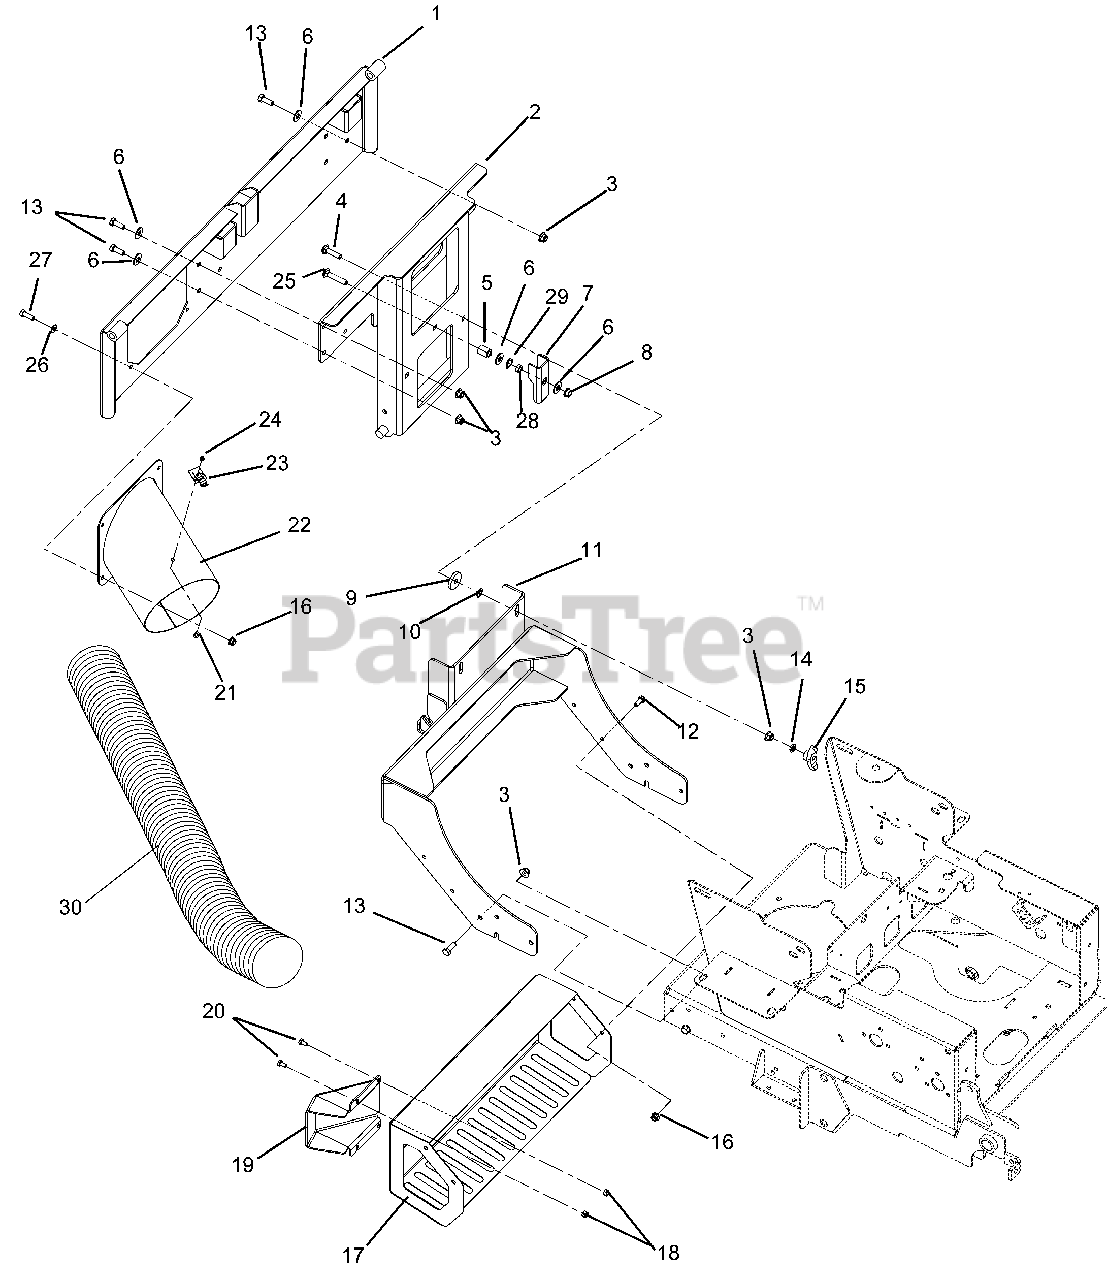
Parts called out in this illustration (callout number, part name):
1	Receptacle, Humboldt 2-Bag
2	Weldment, Upper Mount - 2 Bag
3	Nut, .38-16 Nyloc Flange
4	Bolt, Round Head Square Neck .38-16 x 1.75 Grade 5
5	Bushing, Spacer .41 x .75 x .88
6	Washer, Flat-Steel .438 x 1.00 x .083
7	Latch, Bagger Upper Mount
8	Nut, Locking-Top-Flange .38-16
9	Washer, Flat Steel .406 x 1.50 x .245
10	Nut, Push .38 Dia.
11	Weldment, Lower Mount - 2 Bag
12	Bolt, Hex .31-18 x .75 Grade 5
13	Bolt, Hex .38-16 x 1.00 Grade 5
14	Washer, Locking .375 x .115
15	Nut, Wing .38-16
16	Nut, .31-18 Nyloc Flange
17	Shield, Heat
18	Nut, Locking-Center .25-20
19	Deflector, Exhaust- MZ
20	Bolt, Hex .25-20 x .50 Grade 5
21	Screw, Machine 10-24 x .50 Hex Washer Head
22	Inlet Adapter 100 Series
23	Thumb Latch
24	Nut, Locking-Nylon 10-24 with Insert
25	Bolt, Round Head Square Neck .38-16 x 2.00 Grade 5
26	Washer, Flat-Steel .344 x .688 x .065
27	Bolt, Hex .31-18 x 1.00 Grade 5
28	Bushing, Sleeve .377 x .624 x .235
29	Wave Washer .640 x .875 x .125
30	Hose, 7 x 63
